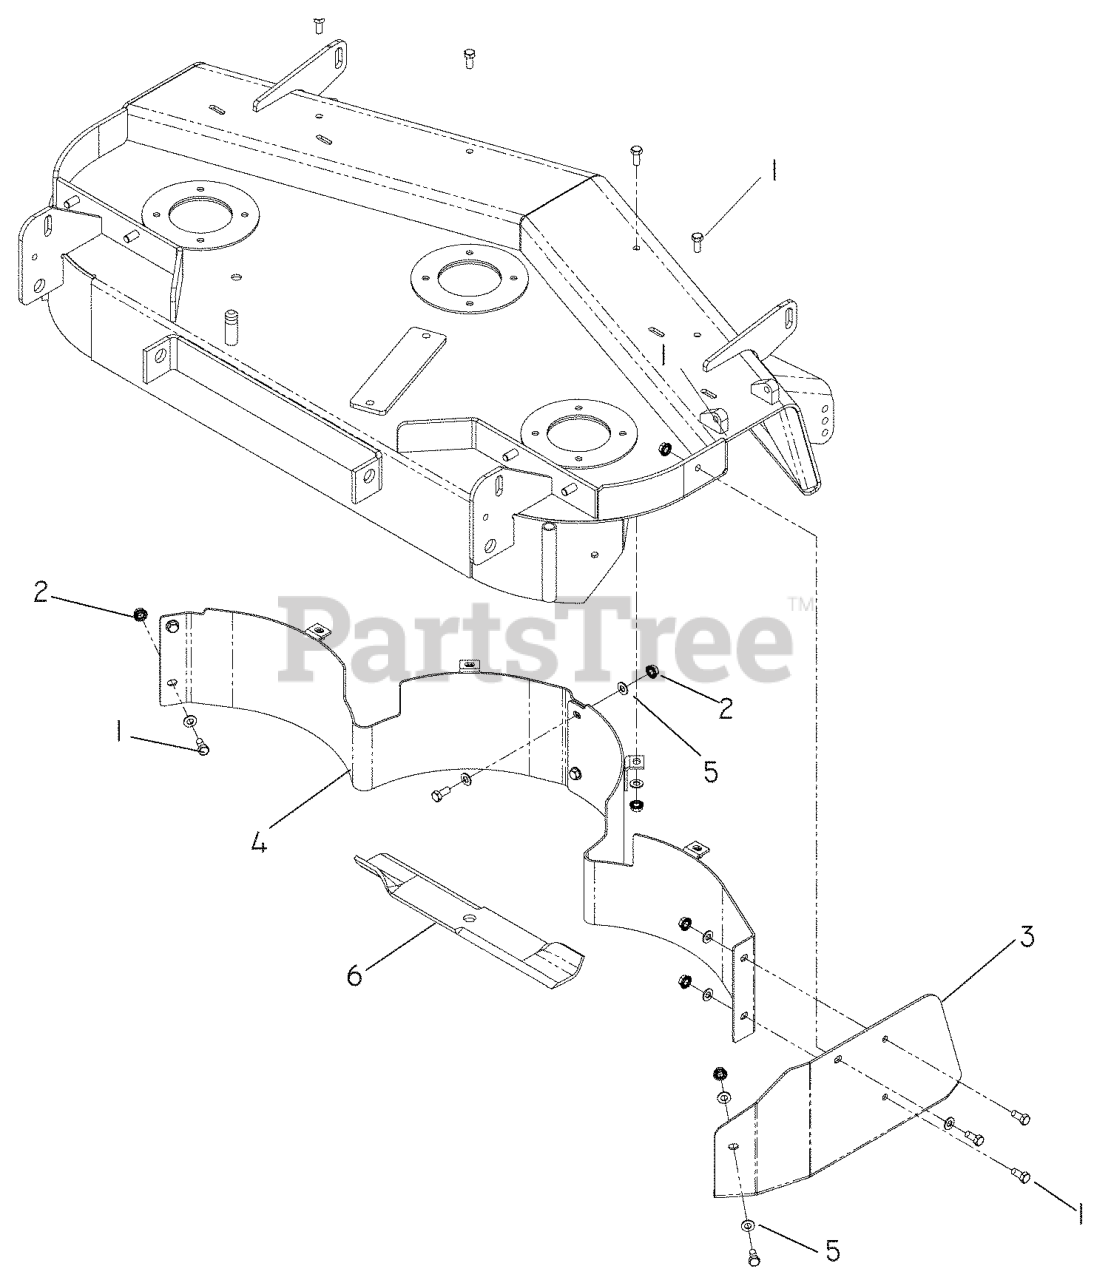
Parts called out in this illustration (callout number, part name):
1	HCS 5/16C X 3/4
2	NUT 5/16C WHIZ
3	BAFFLE WLDMT, 52" R.H. MULCH
4	BAFFLE WLDMT, 52" L.H.
5	FLAT WASHER 5/16 SAE
6	BLADE MULCH 18"
7	MULCH CAP 52
